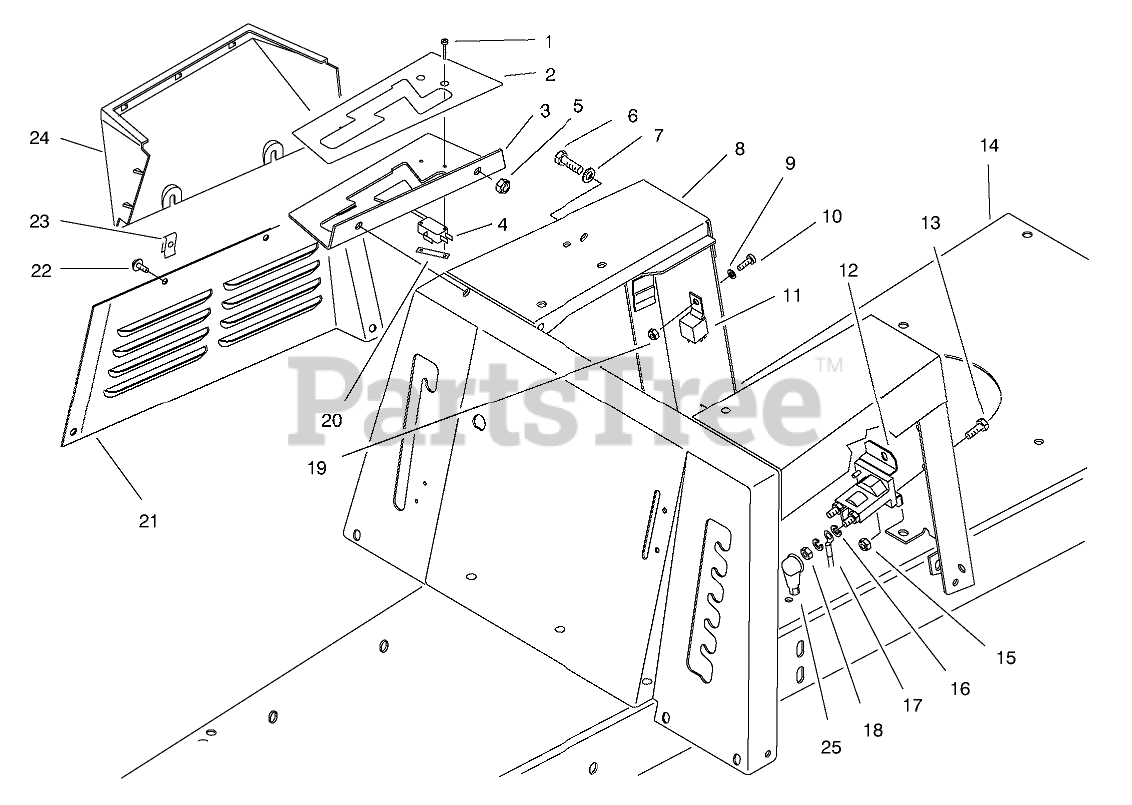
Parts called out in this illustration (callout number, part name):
1	SCREW-HH
2	DECAL - SHIFT PATTERN
3	Gate-Shift
4	SWITCH-MICRO
5	NUT-LOCK, NI
6	SCREW-HH
7	WASHER-PLAIN
8	Body W.A.-Seat Support
9	WASHER-FLAT
11	RELAY
12	SOLENOID
13	SCREW-HH
14	Frame
15	NUT-LOCK, NI
16	WASHER-LOCK
17	WIRE ASM
18	NUT-JAM
19	NUT-LOCK, NI
20	NUT-SPEED
21	Panel-Seat Base, R.H.
22	SCREW-HWH
23	NUT-CLIP,U
24	COVER-SHIFT GATE
25	BOOT-INSULATOR, TERMINAL
